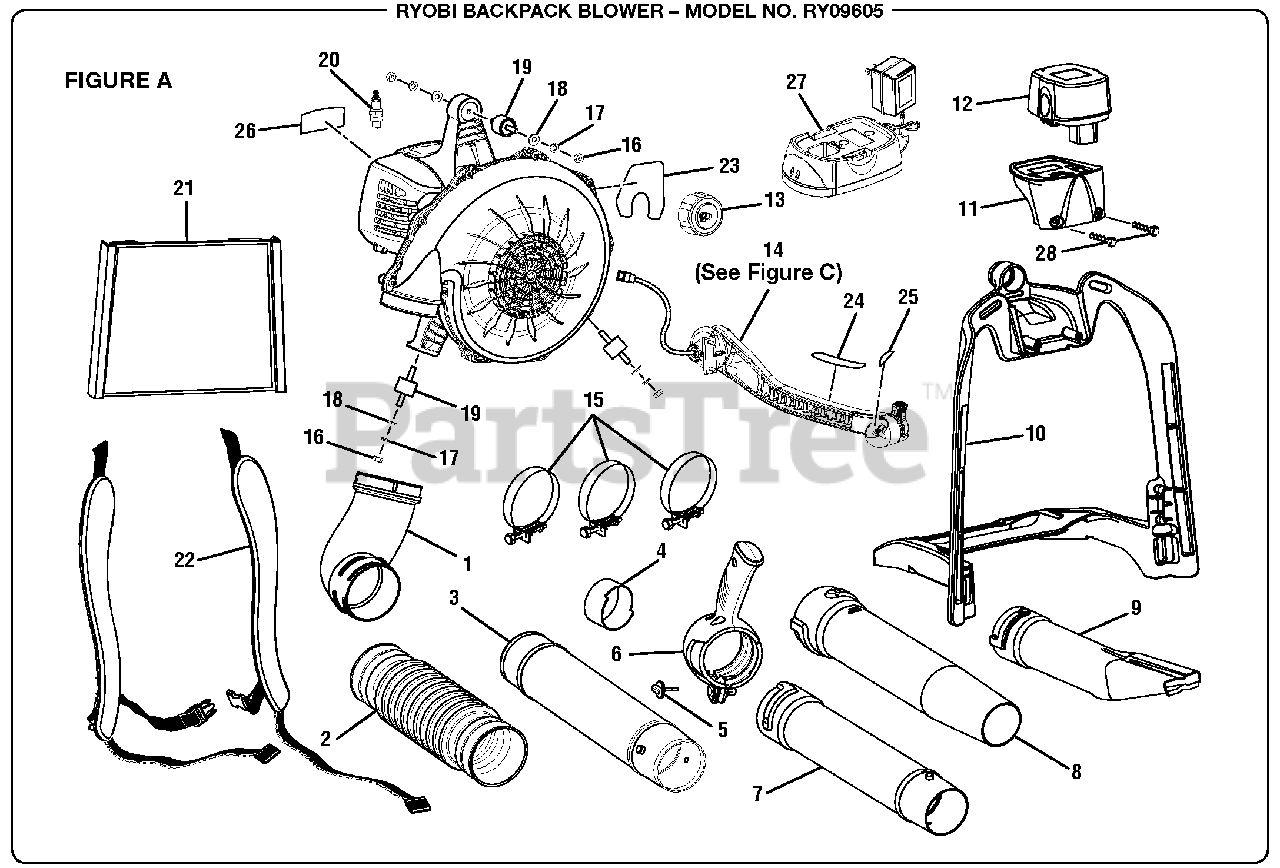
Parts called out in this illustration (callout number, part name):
1	Elbow
3	Upper Tube
5	Thumb Screw
6	Adjustable Handle Assembly (Inc. Key No. 5)
7	Lower Tube
8	Nozzle
9	High Velocity Nozzle w/Leaf Scraper
11	Battery Receiver
12	12 Volt Battery
13	Fuel Cap Assembly
14	Throttle Arm Assembly
15	Tube Clamp
16	Hex Nut (1/4-20)
17	Lock Washer
19	Vibration Isolators
20	Spark Plug (Champion RCJ6Y)
21	Mesh Backing
22	Harness Assembly
23	Starting Label
24	Warning Label
25	Touch Start Label
26	Logo Label
28	Screw (10-24 x 3/4 in.)
